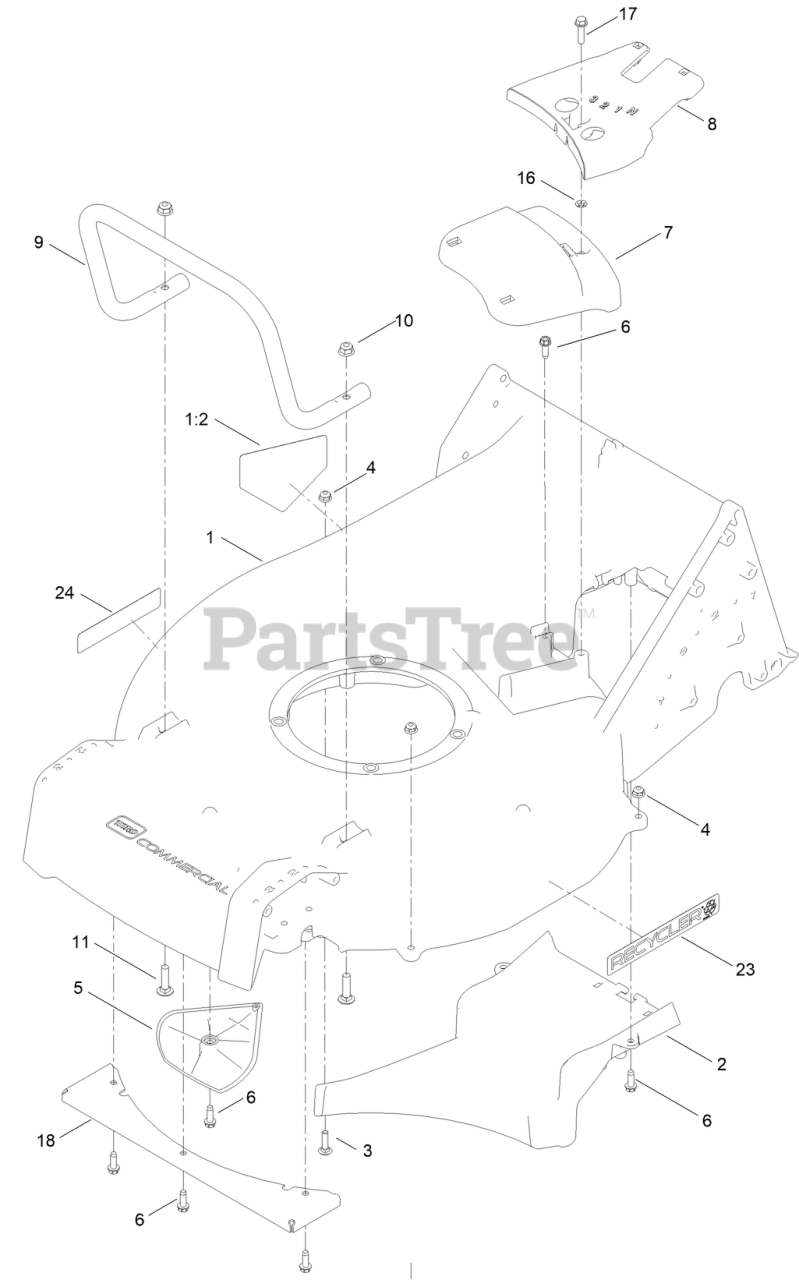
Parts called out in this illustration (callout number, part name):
1	HOUSING ASM
1:2	DECAL-DANGER
2	FLOOR-CHUTE
3	SCREW-CARR
4	NUT-HF
5	KICKER
6	SCREW-HWHTF
7	COVER-BELT, FRONT
8	COVER-BELT, REAR
9	GUARD-ENGINE
10	NUT-HF, NI
11	SCREW-CARR
16	PUSHNUT-RETAINER, BOLT
17	SCREW-HWHTF
18	GUARD-TOE, FRONT
23	DECAL-RECYCLER
